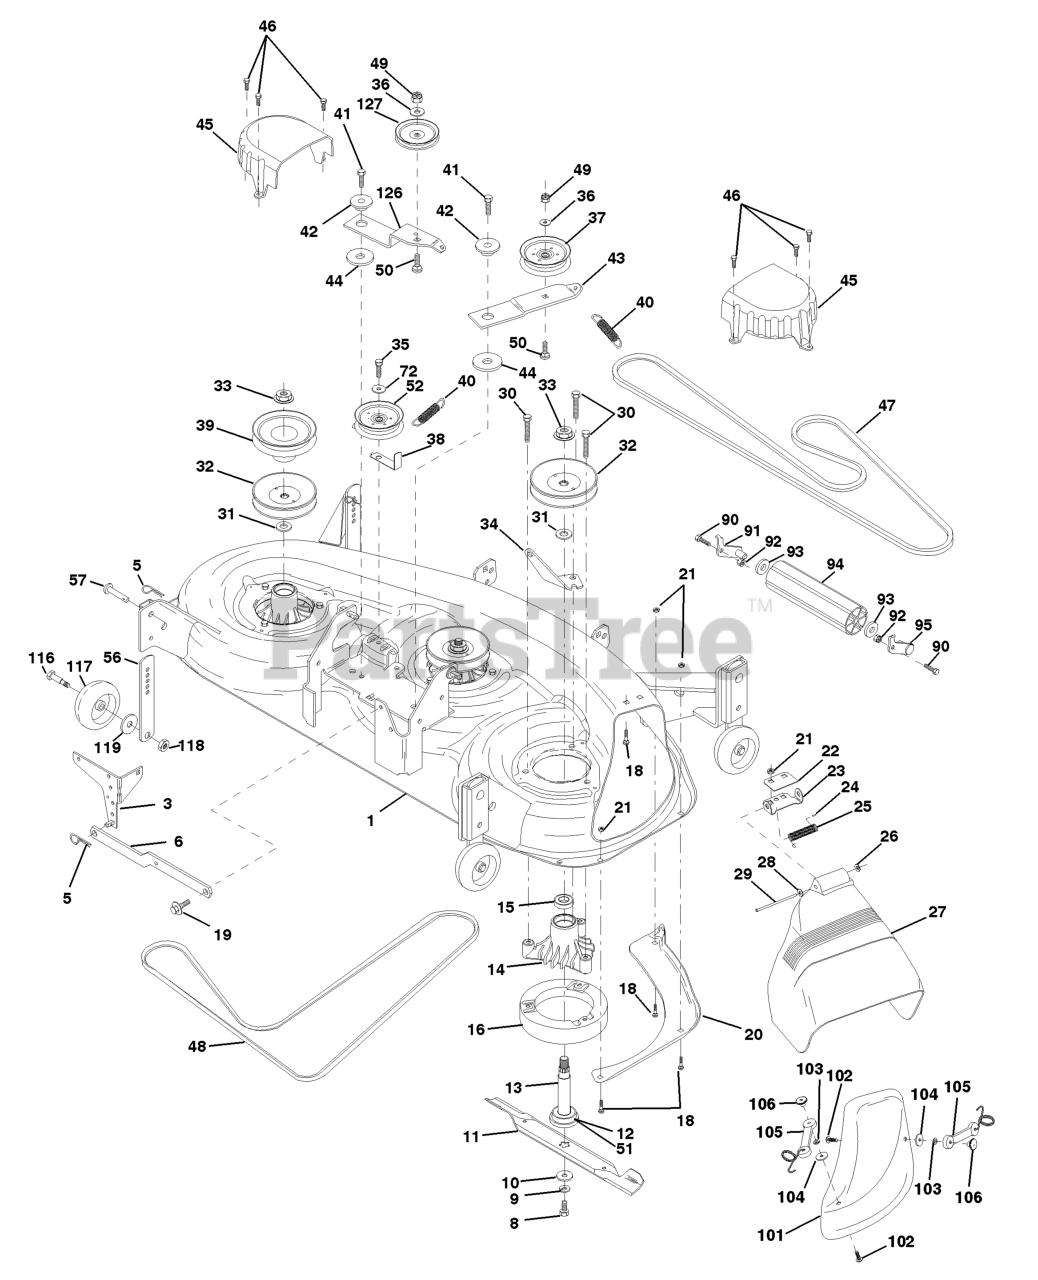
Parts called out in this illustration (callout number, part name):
1	DECK
3	BRACKET SWAY BAR
5	RETAINER-SPRNG RB
6	REAR SUSP ARM
8	BLADE BOLT
9	LOCKWASHER
10	WASHER.BLADE
11	MULCH BLADE
12	BEARING.BALL.#6204.(MANDREL)
13	SHAFT.ASM.W/BEARING
14	HOUSING.MANDREL.44/46" VENT
16	STRIPPER
18	BOLT
19	BOLT SHD 5/16-18
20	BAFFLE, VORTEX MOWER 46"
21	LOCKNUT
22	STIFFENER BRACKET
23	DEFLECTOR BRACKET
24	CAP-SLEEVE LT
25	TORSION SPRING
26	NUT PUSH M
27	DEFLECTOR SHIELD
28	Washer 11/32 x 5/8 x 16 Ga.
29	ROD.HINGE
30	SCREW THDROL ROLLING WASHER HD
31	WASHER
32	PULLEY, MANDREL
33	NUT
34	ANCHOR, SPRING DECK 46"
35	SCREW LT
36	WASHER
37	FLAT IDLER PULLEY
38	KEEPER.BELT.IDLER
39	PULLEY.DRIVEN.DECK.46"
40	SPRING.SEC.44"VEN
41	SCREW
42	SPACER RETAINER
43	ARM IDLER DECK 46"
44	HARDENED WASHER
45	COVER MANDREL 46
46	SCREW.1/4-20X5/8
47	BELT V SECONDARY
48	V-BELT PRIMARY 50"
50	BOLT.3/8-16X1.50
51	WASHER FELT
52	PULLEY IDLER FLAT 46 PRI DRIVE
56	BAR.ADJUST.WHEEL.ANTI.SCALP.BL
57	RIVET.PIN.HEAD.YELLOW.
72	WASHER
90	BOLT
91	BRACKET LH (A)
92	NUT
93	Washer 17/32 x 7/8 x 16 Ga.
94	NOSE ROLLER
95	BRACKET RH (B)
101	COVER.MULCH.46"3-BLADE.(2 2)
102	SCREW
103	LOCKWASHER #10
105	LATCH ASSY
106	WELDNUT
116	BOLT, SHOULDER
117	WHEEL GAGE DONUT
118	LOCKNUT
119	WASHER.5/16.FLAT.STE.STD.
126	ARM IDLER PRIM 46
127	PULLEY.IDLER.4.25
128	Washer 13/32 x 1-3/8 x 3 Ga.
